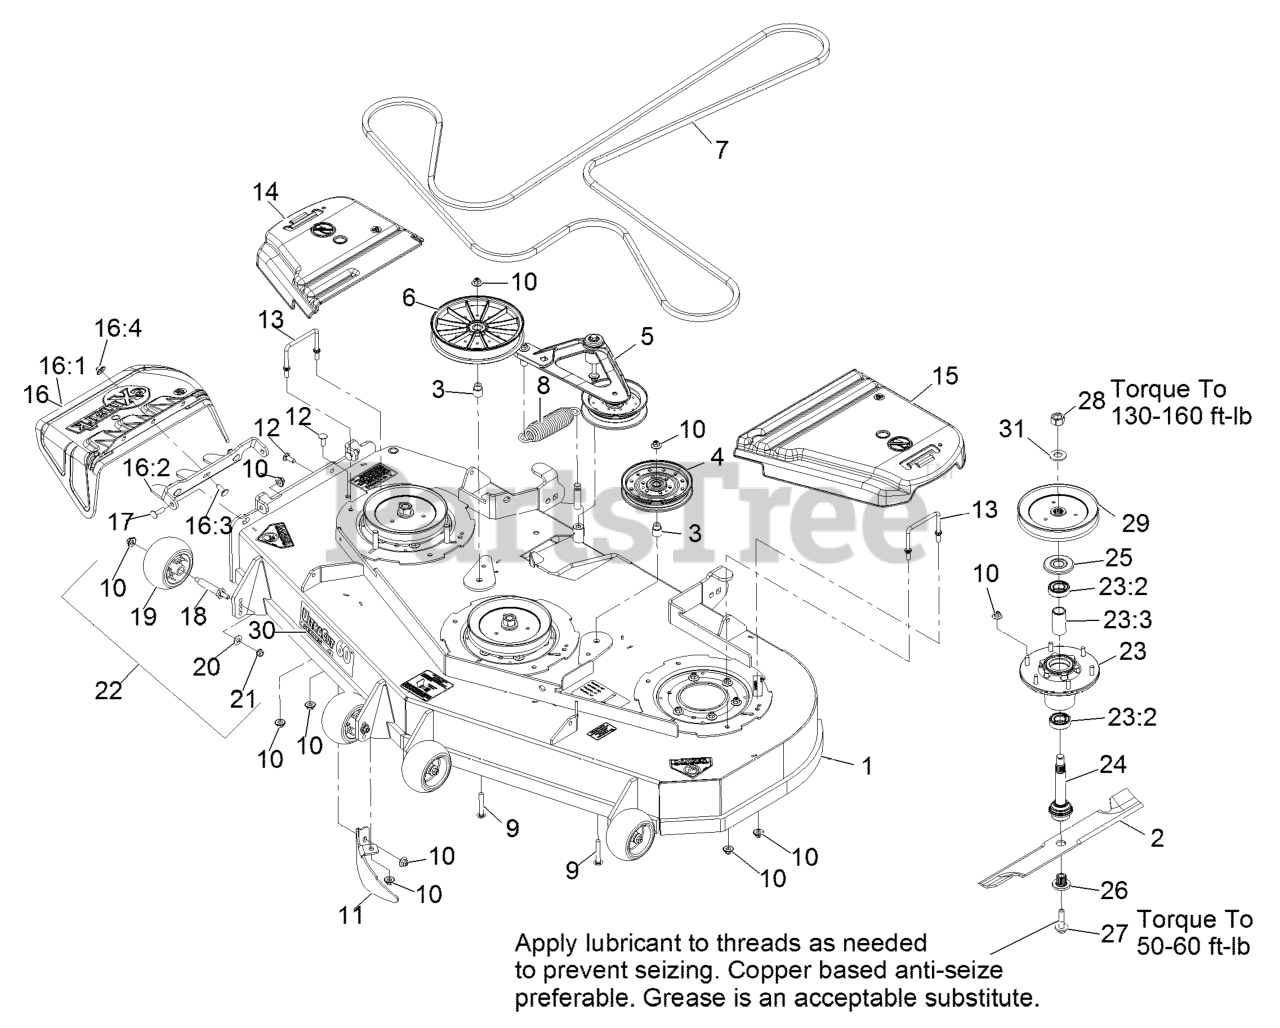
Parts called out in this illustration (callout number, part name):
1	DECK ASM,W/DECALS 60
2	Blade-Extreme 2, 20.50"
3	BUSHING-IDLER
5	DECK IDLER ASM
6	PULLEY,IDLER 8"FLAT
7	BELT,V-5V-198.75
8	SPRING-EXTENSION
9	SCREW-CARR
10	Nut-Nyloc 3/8-16 Flg
11	DOGLEG - LZ60
12	SCREW-CARR
13	WIREFORM-COVER
14	COVER-BELT, RH
15	COVER-BELT, LH
16	ASM,DISCHARGE CHUTE
16:1	CHUTE,DISCHARGE
16:2	BRACKET,DISCHARGE CHUTE
16:3	SCREW-CARR
16:4	Nut-Nyloc 3/8-16 Flg
17	Bolt-Carriage 3/8-16 X 1 1/4
19	ROLLER-SCALP, ANTI
20	WASHER-BELLEVILLE
21	NUT-HHF, WHIZ
23	ASM-CUTTER HSG WITH BEARINGS
23:2	BEARING-BALL
23:3	SPACER-BEARING
24	ASM-SPINDLE AND SEAL
25	GUARD,BEARING TOP .989
26	BUSHING,SPLINED
27	SCREW,SEMS 1/2-20 X 2.19
28	NUT-HEX
29	SHEAVE,BLADE DRIVE 7.25
30	DECAL,ULTRACUT 60 SERIES
